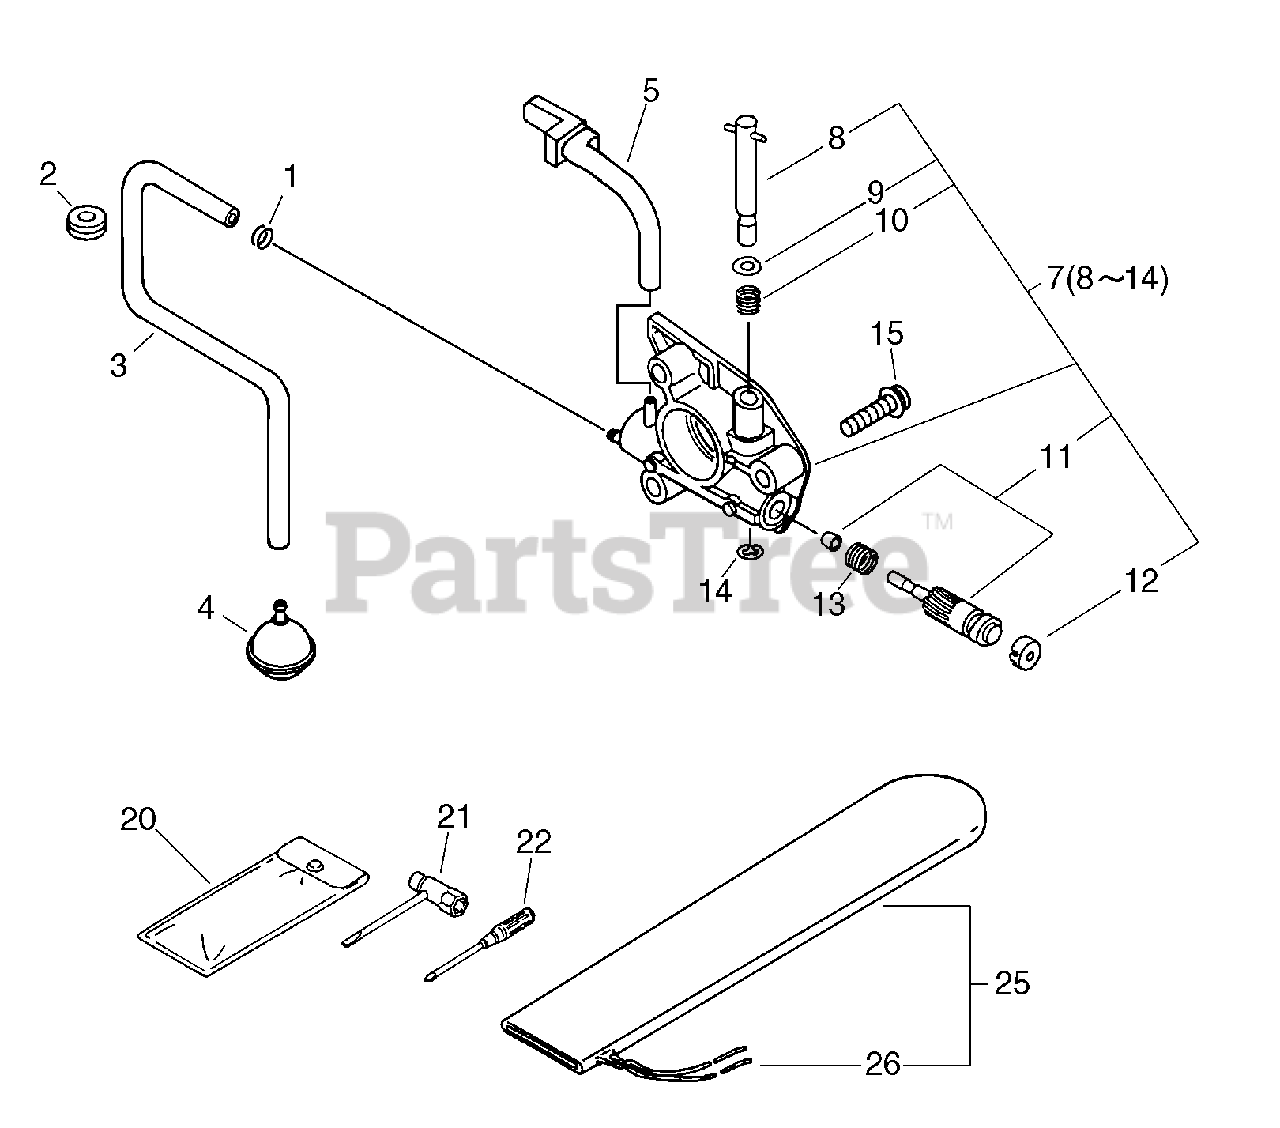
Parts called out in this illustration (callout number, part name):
1	CLIP - 6.5
3	PIPE
4	FILTER, OIL
5	PIPE - OIL
7	AUTO-OILER ASSY
8	NEEDLE, ADJUST
12	CAP, OIL PUMP
14	RING, RETAINING
20	BAG, TOOL
21	T-WRENCH - 10X19mm
22	SCREWDRIVER
25	COVER, GUIDE BAR
